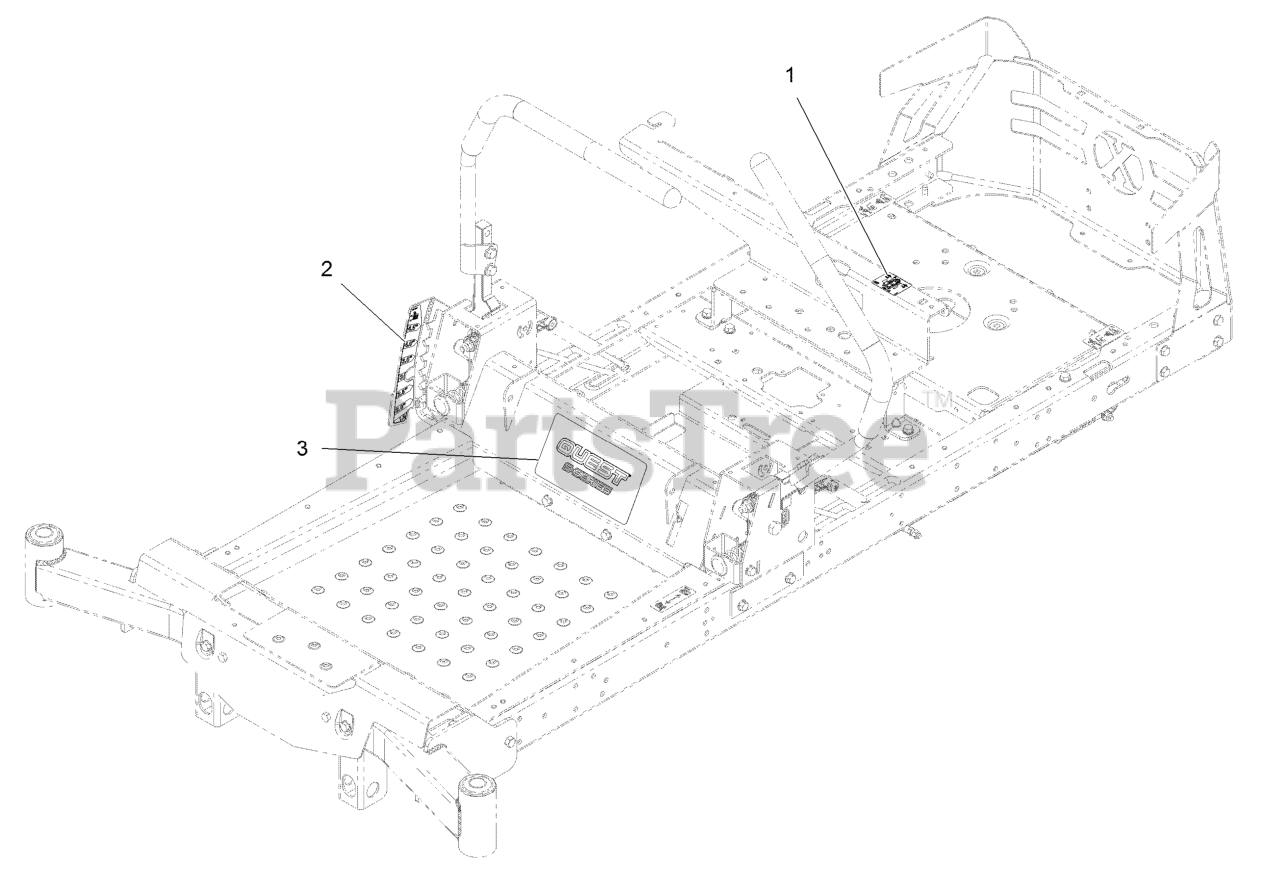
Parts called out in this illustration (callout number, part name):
1	Decal-Service, CE
2	Decal-HOC
3	Decal, Quest S Series
